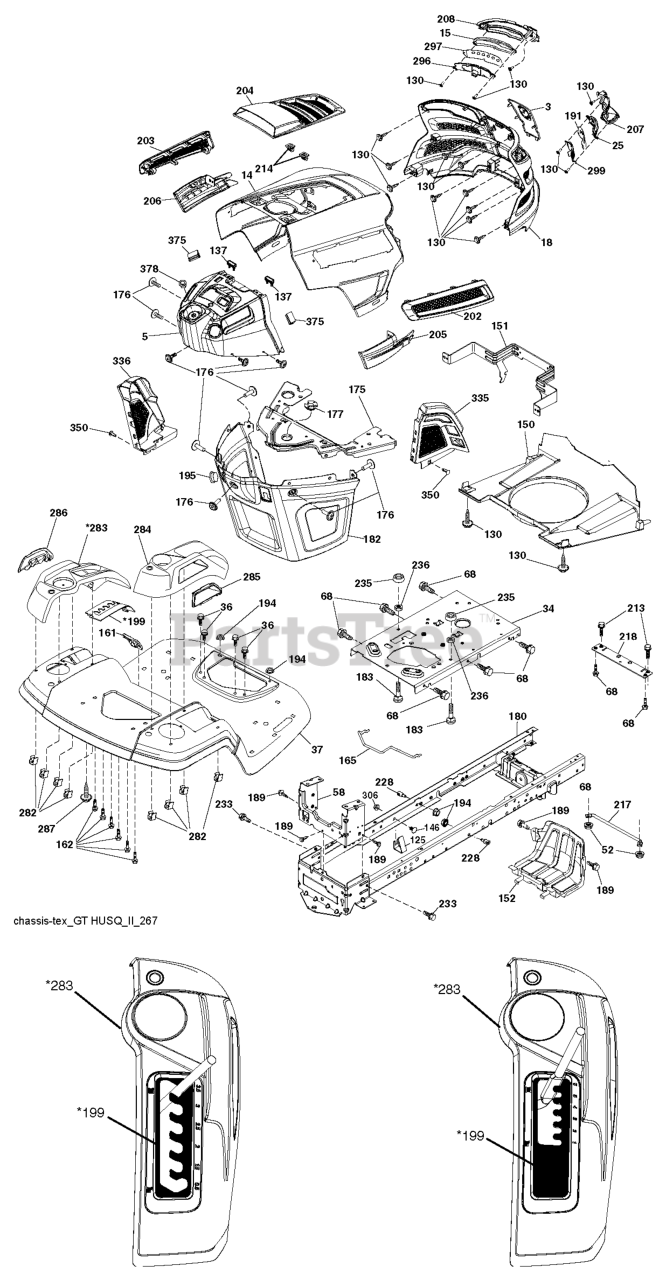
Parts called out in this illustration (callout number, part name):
3	APPLIQUE.SUBASM.GT.HUSQ.II
5	DASHBOARD.TEX.GT2.UPPER.S.PTO
14	HOOD.ASM.HUSQVARNA.GT.TEX.ORAN
15	LED LIGHT.LH
18	GRILLE SUBASM.GT.II.LOW.HDLGHT
25	LENS.RH
34	PLATE.ENGINE.WELDED.CHASSIS
36	SCREW 5/16"
37	FENDER.TLT.FS.W/CPH/FW/RSF.668
52	LOCKNUT
58	DRAWBAR UPPER 2PC SMALL FENDER
68	SCR 5/16-18 X 1/2 SELFTAP ZN
125	CLIP.FUEL.LINE
130	SCREW.#10 X 0.750.BOS
137	BUMPER DASH
146	BOLT.RDHD.SHT.SQNK.3/8-16X5/8
150	AIR.DUCT.GTV.BLACK
151	BRACKET.PIVOT.HOOD.GT.HUSQ.II
152	SHIELD.BROWNING.PNT.GT.V2
161	WINDOW.FUEL.LT.HUSQ.TEX.498
162	SCREW.HI-LO.CONSOLE
165	SUPPORT.TANK.REAR.W/TEX
175	PLATE.PNT.CROSSMEMBER.HUSQ/PRE
176	SCREW.#10-24X5/8.RN.QU
177	BUSHING STEERING
180	CHASS.WLDMNT.TL.12GA/2P.48/54
182	DASH.LOWER.COMMON.12V.ADAPTOR
183	BOLT.5/16-18X1-1/4 FULL THD
189	SCREW
191	INSERT INFLECT.RH
194	NUT LOCK HEX FLANGE 5/16-18
195	PLUG.HOLE.DASH.LOWER.12V.BLK
202	VENT.SIDE.RH.GT.HUSQ.II.
203	VENT.SIDE.LH.GT.HUSQ.II.498
204	VENT.TOP.HUSQ.GT2
205	SIDE.TRIM.RH.GT.HUSQ.II
206	SIDE.TRIM.LH.GT.HUSQ.II.GRAY
207	BEZEL GT2 LED RH W/ LOWER.ATT
208	BEZEL GT2 LED LH W/ LOWER ATT
213	BOLT
214	CLIP.RETAINER.TINNER.
217	ROD.PIVOT.HOOD
218	X-PIECE.HOOD.STOP.NON/
228	STUD.FASTNER.W/ANTI-ROTATE
233	BOLT.SHOULDER
235	SPACER FENDER
236	NUT.CENTERLOCK.5/16-
282	CLIP.RETAINER.CONSOLE.LT.HUSQ
284	CONSOLE.ASM.LFT.RSF.HUSQ.LT
285	CONSOLE INSERT RH
286	CONSOLE INSERT LEFT
287	SCREW 1/4X20
296	LED LIGHT.LH
297	INSERT REFECT LH
299	LED LIGHT.RH
306	NUT LOCK FLG 3/8-16 UNC
335	COVER.LOWER.DASH.RH.BLACK
336	COVER-LH.LOWER.DASH.GT2.BLACK
350	CLIP.X-MAS.TREE
375	BUMPER CLIP-ON. DASH 1"
378	BUSHING FLANGE; PLASTIC
